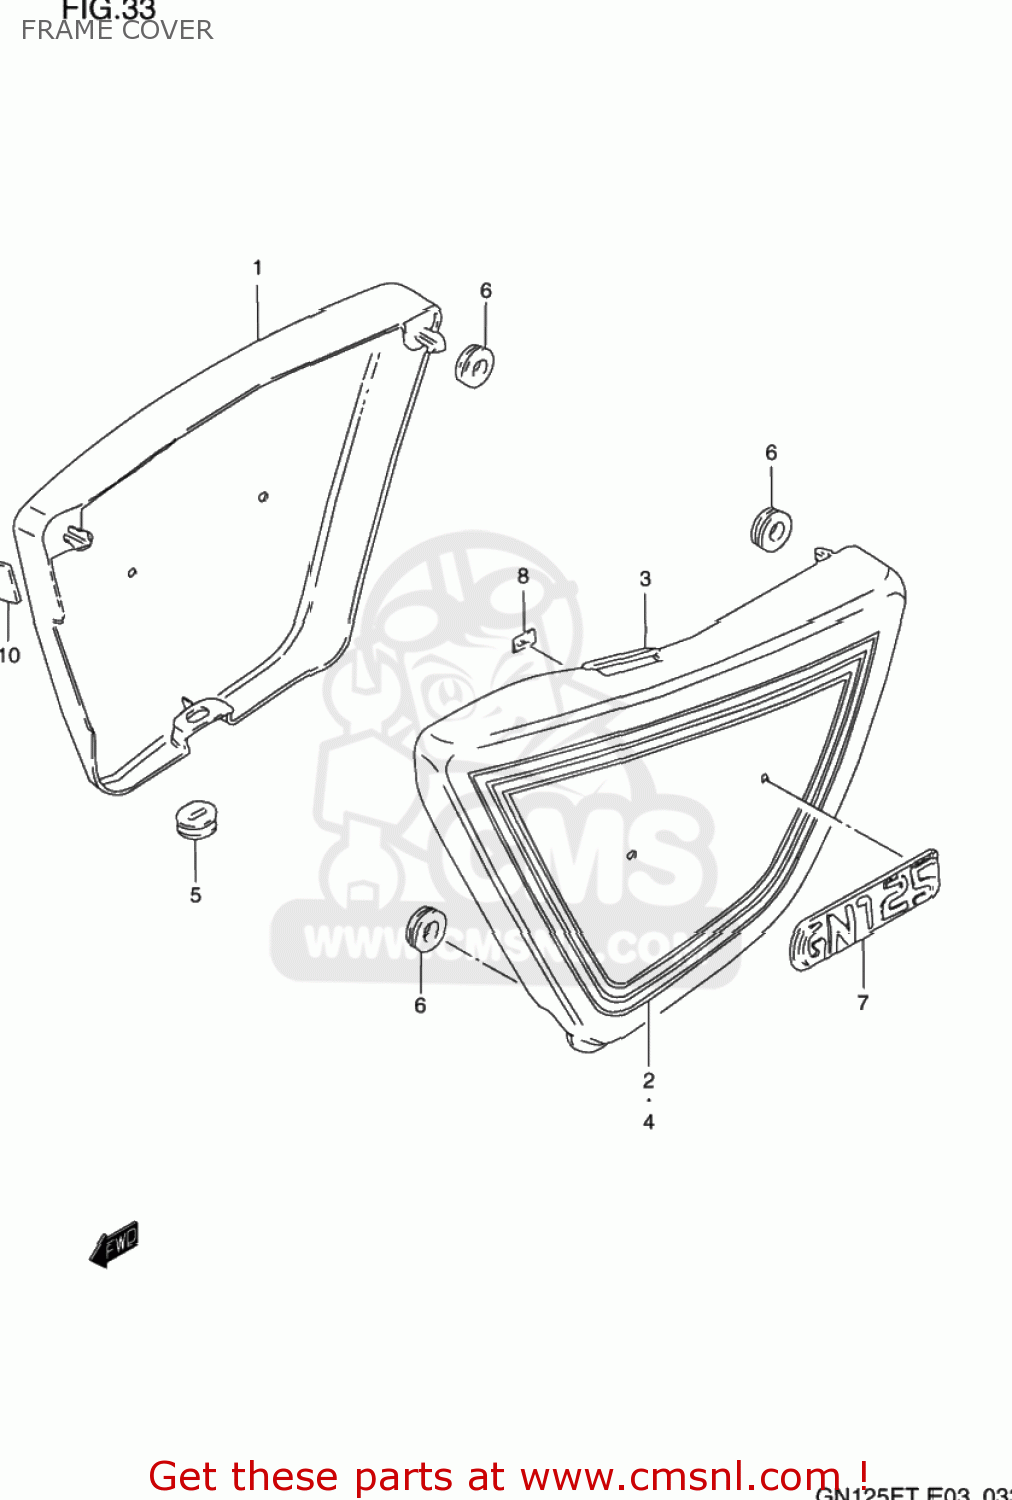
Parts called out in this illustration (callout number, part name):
1	COVER,FRAME,RIGHT
2	TAPE SET,FRAME COVER
3	COVER,FRAME,LEFT
4	TAPE SET,FRAME COVER
5	CUSHION
6	CUSHION
7	EMBLEM,FRAME COVER
8	NUT
9	PROTECTOR(12X40)
